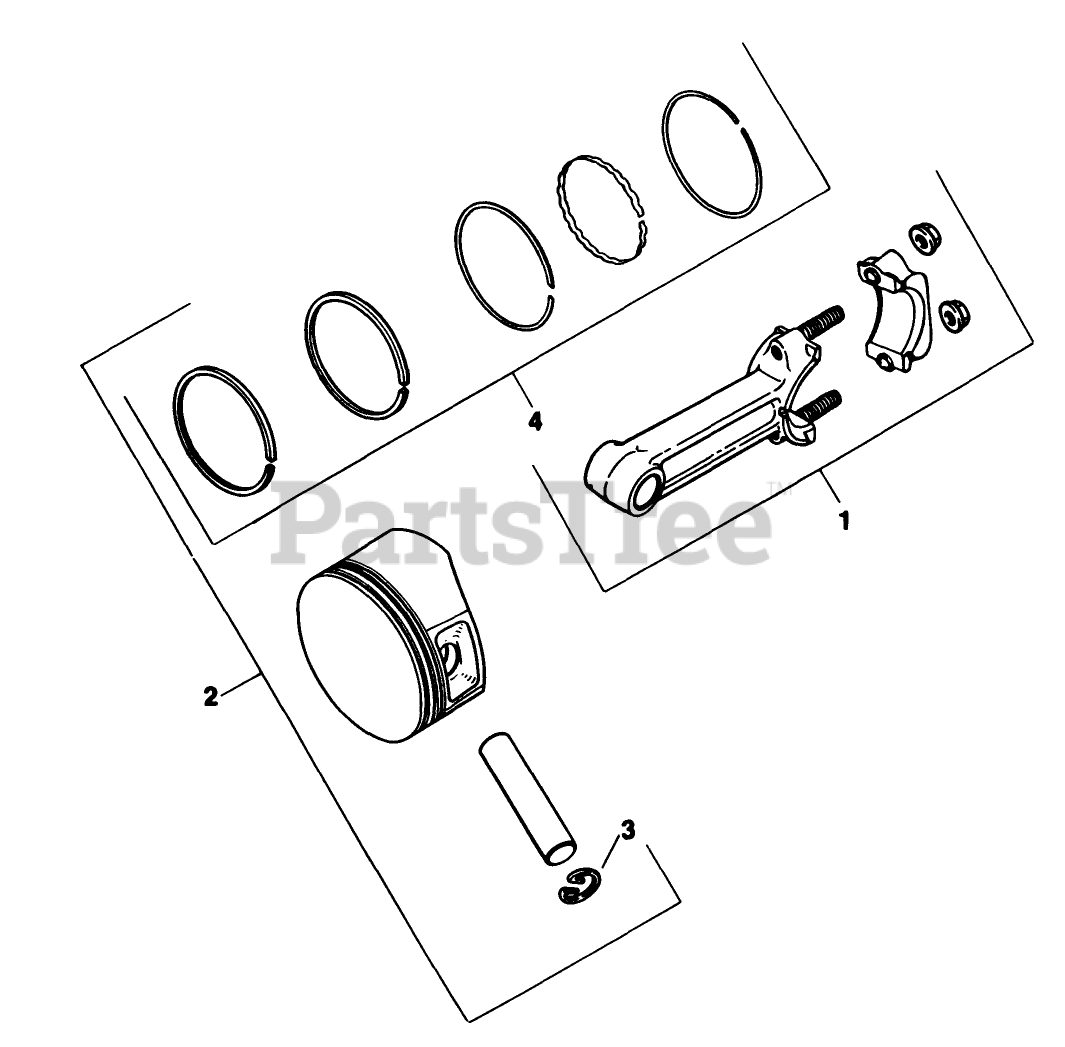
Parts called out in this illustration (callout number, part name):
1	Rod-Connecting Std.
2	Piston Ring Set Std.
3	Retainer, Pin
4	Ring Set (Std. .003)
